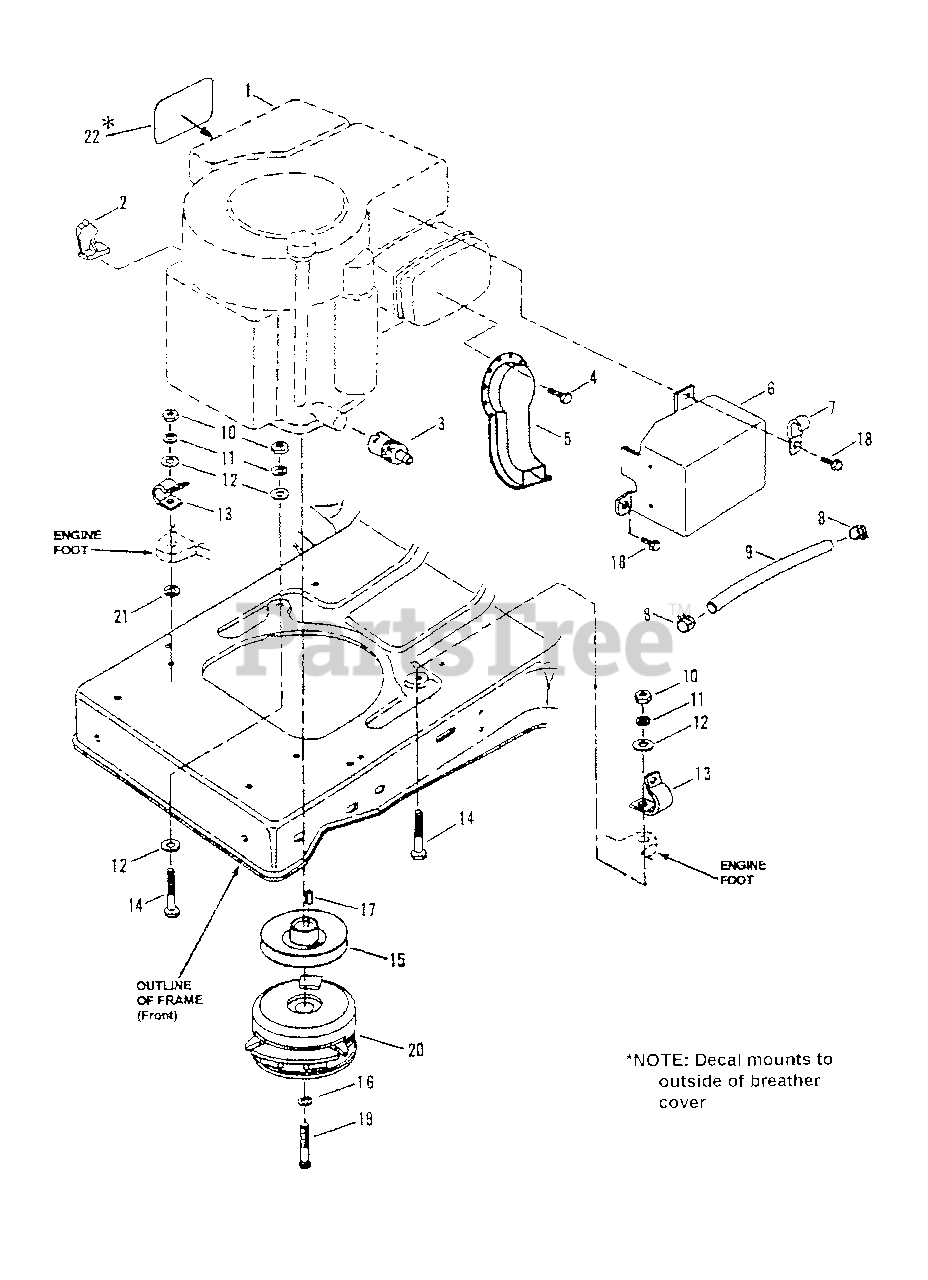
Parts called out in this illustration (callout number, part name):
2	CLIP, Speed (250 RPM Briggs)
3	ASSEMBLY, Oil Valve
4	SCREW, #8-18 x 1/2" Hex Head Sheet Metal
5	WELDMENT, Muffler Deflrctor
6	HEAT SHIELD, Muffler (weldment)
7	CLIP, "J" Open Type .4 Bundle Dia., .281 Dia. Hole
8	CLAMP, .490 x .31
9	FUEL LINE, 14" long
9	FUEL LINE, 10" long
10	NUT, 5/16-18 Hex, GR5 or B
11	WASHER, 5/16" Split Lock
12	WASHER, 5/16" Flat
13	HARNESS CLIP, Cushioned
14	SCREW, 5/16-18 x 1-3/4" Hex Head Cap, GR5
15	PULLEY, Traction Drive
16	WASHER, 7/16" Split Lock
17	KEY, 1/4 Square x 3/4"
18	SCREW, 1/4-20 x 1/2" Hex Flange Lock
19	SCREW, 7/16-20 x 2-1/2" (Special), GR5
20	CLUTCH/BRAKE
21	WASHER, 5/16" Internal Tooth Lock
22	DECAL, Warning-Speed Setting 14, 16, & 18 HP ENGINES
